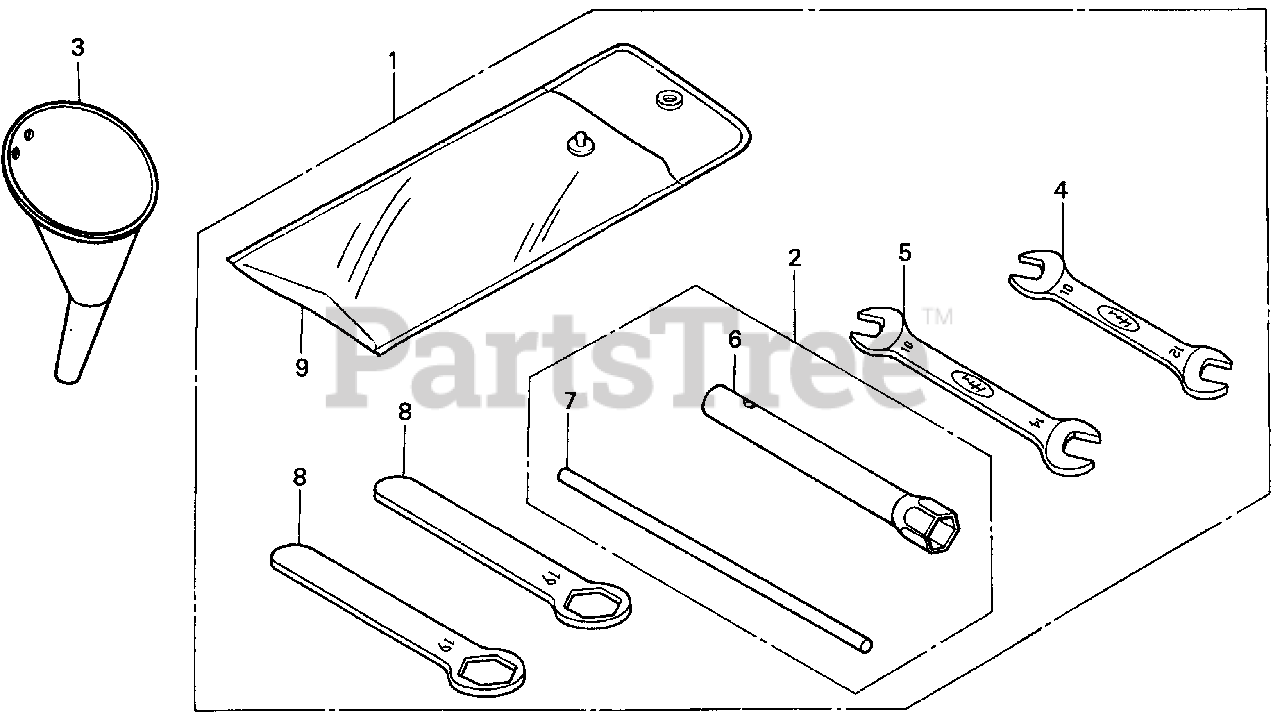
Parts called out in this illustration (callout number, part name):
1	TOOL KIT
2	TOOL KIT
3	FUNNEL, OIL
4	WRENCH (10X12) (OPEN END)
5	WRENCH (10X14) (OPEN END)
6	WRENCH, BOX (P21)
7	BAR A, HANDLE
8	WRENCH, EYE (19MM)
9	BAG, TOOL
